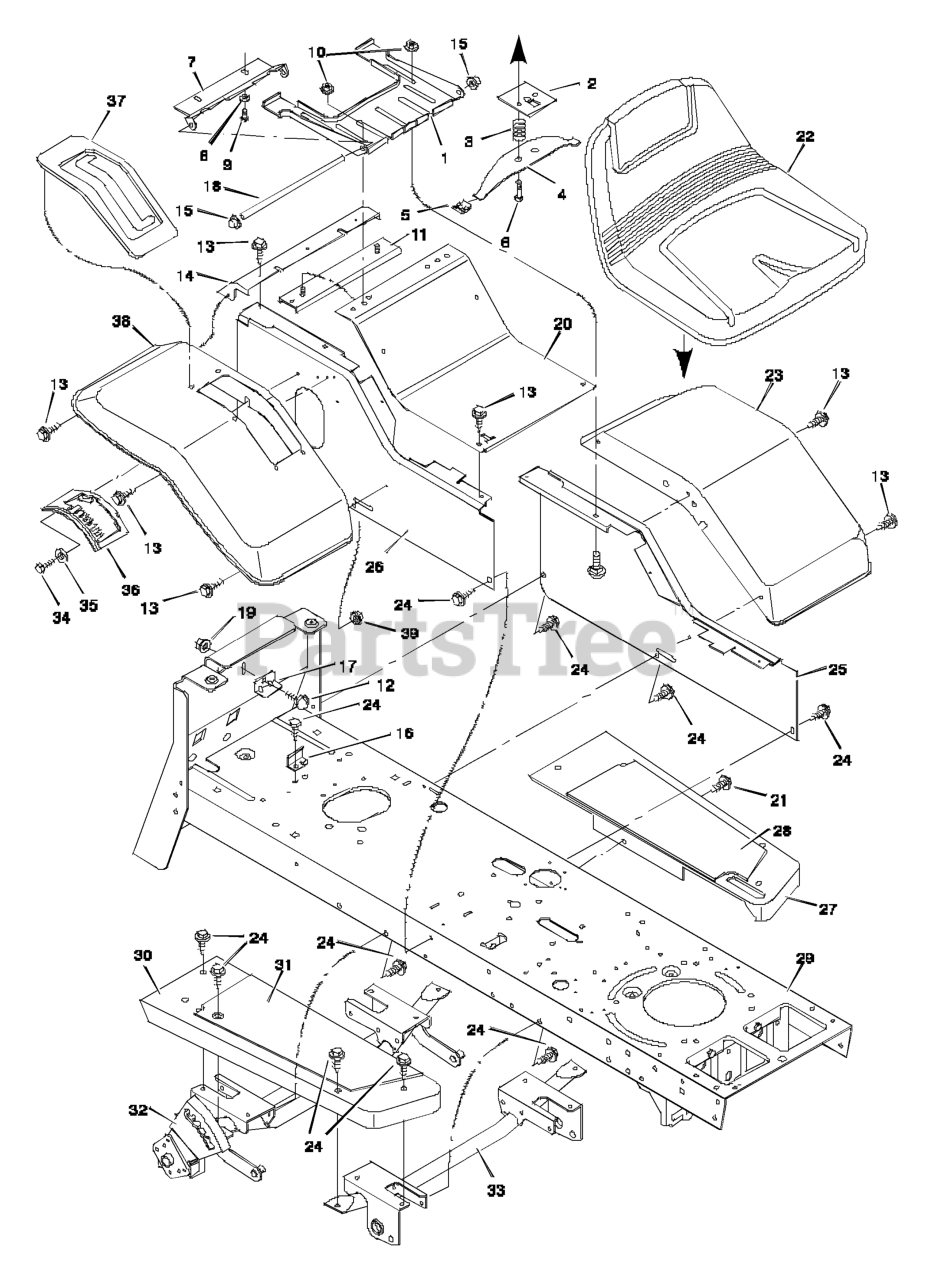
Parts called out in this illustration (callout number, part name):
1	Bracket, Seat
2	Plate Assembly, Switch
3	Spring, Compression
4	Spring, Seat
5	Glide, Spring
6	Bolt, Shoulder
7	Support, Seat
8	Lockwasher
9	Bolt, Hex
10	Locknut, Flange
11	Channel Assembly
12	Bolt, Carriage
14	Insert, Rear
15	Push On Cap
16	Clip, Battery
17	Clamp, Battery
18	Rod, Pivot
19	Locknut
20	Panel, Top
21	Fastener, Panel
25	Panel, Left
26	Panel, Right
27	Running Board, Left
28	Mat, Left
29	Frame Channel
30	Running Board, Right
31	Mat, Right
32	Lifter and Support Assembly
33	Support Assembly, Front
36	Gate, Shift
37	Cover, Shift
38	Fender, Right
39	Locknut
